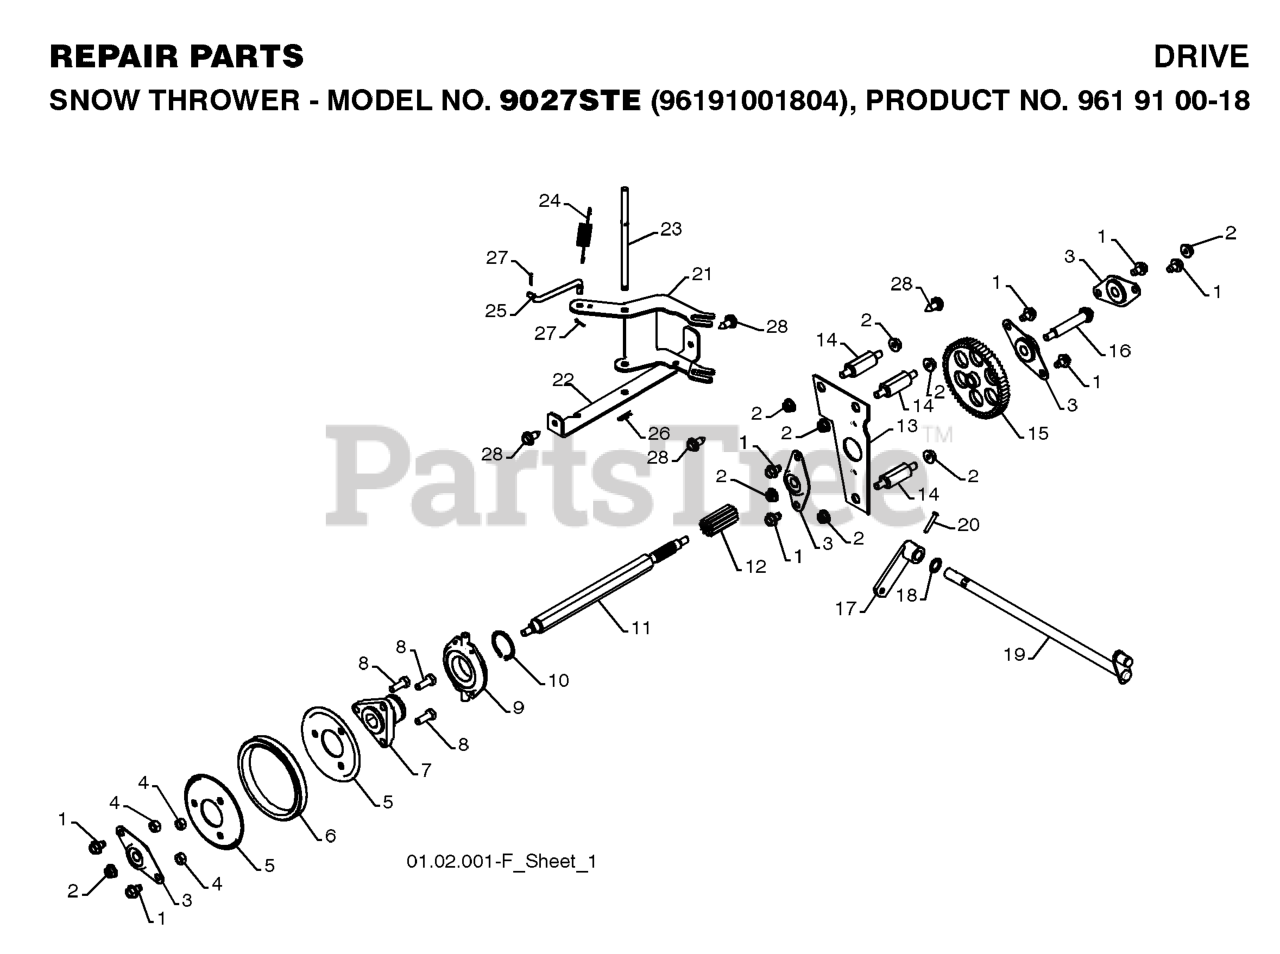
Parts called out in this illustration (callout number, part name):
1	Screw 5/16-18 x 1/2 Hex, Self Tapping 5/16-18 x 1/2
2	NUT.LOCK.5/16-18
3	BEARING, FLANGE
4	NUT.CENTERLOCK.5/16-
5	PLATE.RUBBER.WHEEL
6	RING, RUBBER WHEEL
7	HUB, RUBBER WHEEL
8	BOLT
9	TRUNNION BEARING ASSY
10	RETAINING RING (2 2)(3 2)
11	SHAFT.HEX.LONG
12	GEAR, PINION
13	AUXILLARY PLATE
14	SPACER, PLATE
15	GEAR, INTERMEDIATE
16	SHAFT, AUXILIARY
17	ARM, AUGER CONTROL
18	THRUST WASHER
19	SHAFT, AUGER CONTROL
20	CLEVIS PIN
21	LEVER, SPEED CONTROL
22	BRACKET, PIVOT, SHIFT
23	PIN, PIVOT
24	SPRING, BIAS
25	LINK, SPEED CONTROL
26	RETAINER CLIP PM
27	RETAINER CLIP
28	SELF-TAPPING SCREW 5/16-18X3/4
